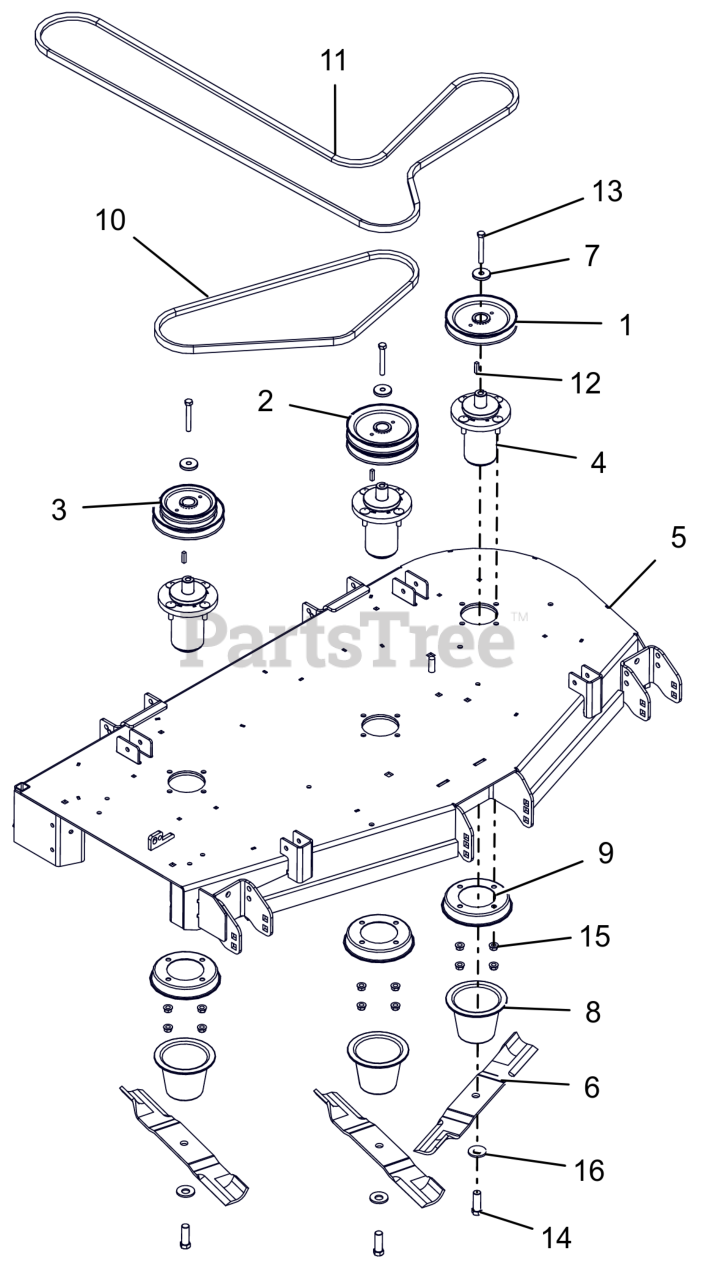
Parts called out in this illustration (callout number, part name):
1	PULLEY, SINGLE-1"ID X 6" OD
2	PULLEY, DOUBLE
3	PULLEY, DBL-1"IDX6.00"&4.75"OD
4	ASM, MAINT FREE ALUM SPINDLE
5	WLDMT, 52" SIDE DISCHARGE DECK-RED
6	BLADE, 18.00" MOWER (HI-LIFT)
7	RETAINER, SHEAVE
8	GUARD, SPINDLE LOWER
9	GUARD, SPINDLE TOP
10	V-BELT, B-COGGED
11	V-BELT, HB RAW EDGE EPDM
12	KEY, SQ .25X.25X1.00 RC 40-50
13	BLT, HEX .38-16X2.75 G8 ZCC
14	BLT, HEX .62-18X1.75 G8 ZCC
15	NUT-LK-CTR-FLG .375-16 GF ZCC
16	WSHR-BLVL .669X1.535X.138
